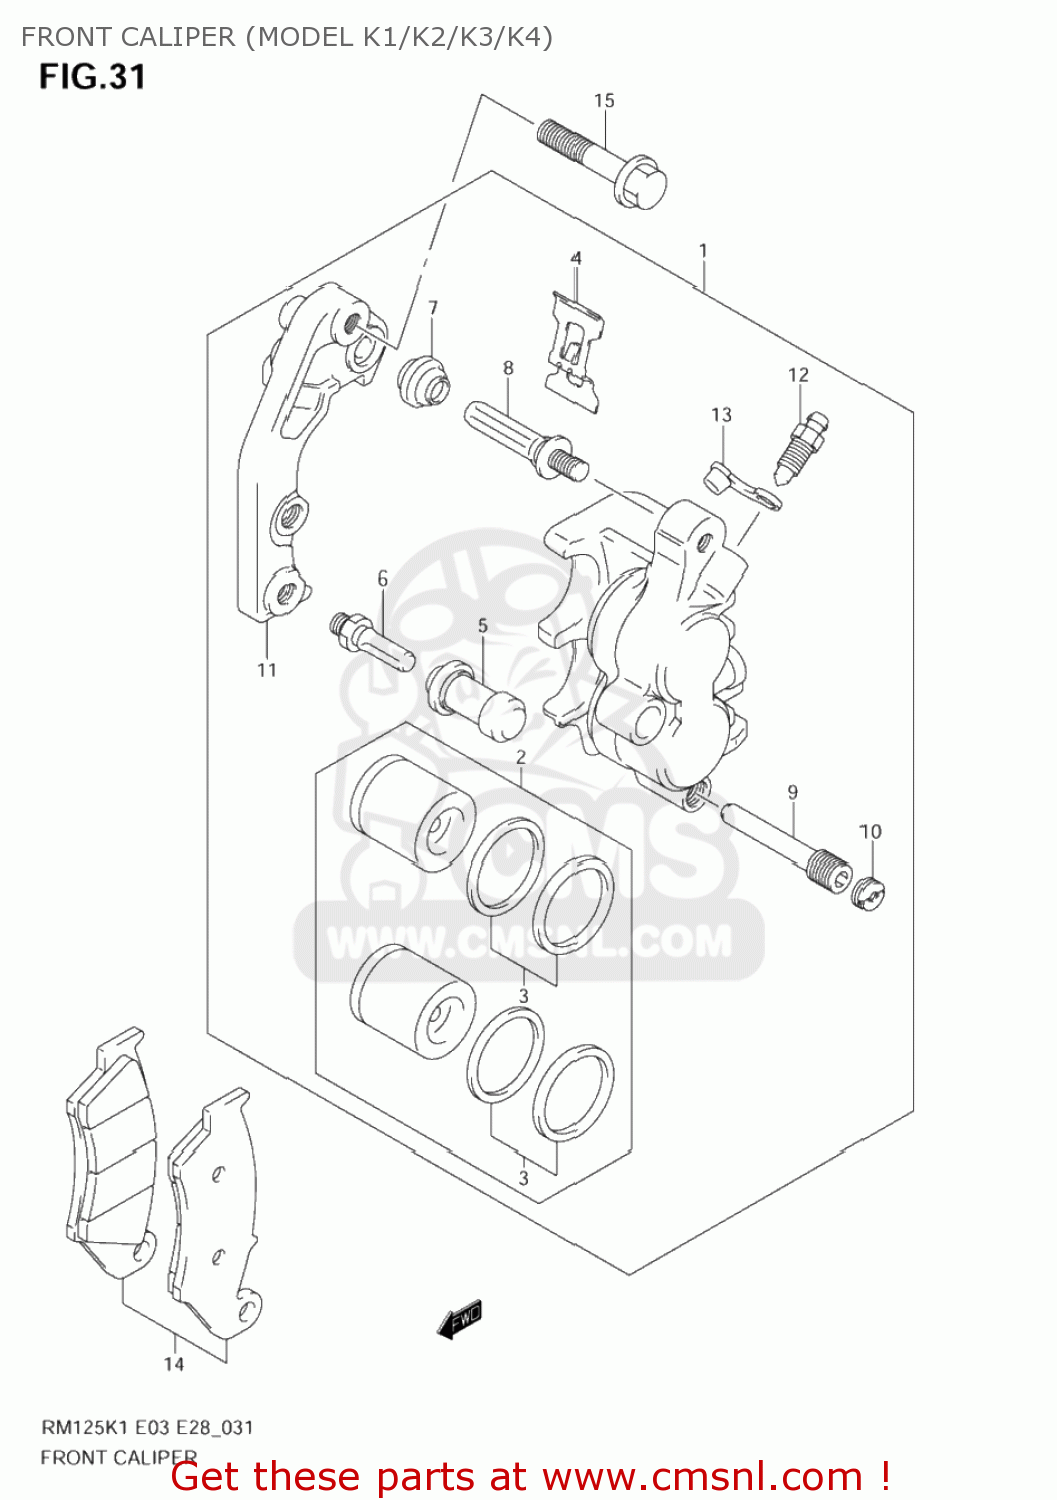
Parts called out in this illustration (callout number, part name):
1	CALIPER ASSY, FRONT
2	PISTON SET
3	SEAL SET,PISTON
4	SPRING,PAD
5	BOOT
6	BOLT
7	BOOT
8	PIN
9	PIN,HANGER
10	PLUG,PIN
11	BRACKET
12	BLEEDER
13	CAP,BLEEDER
14	PAD SET (NAS)
15	BOLT(8X40)
